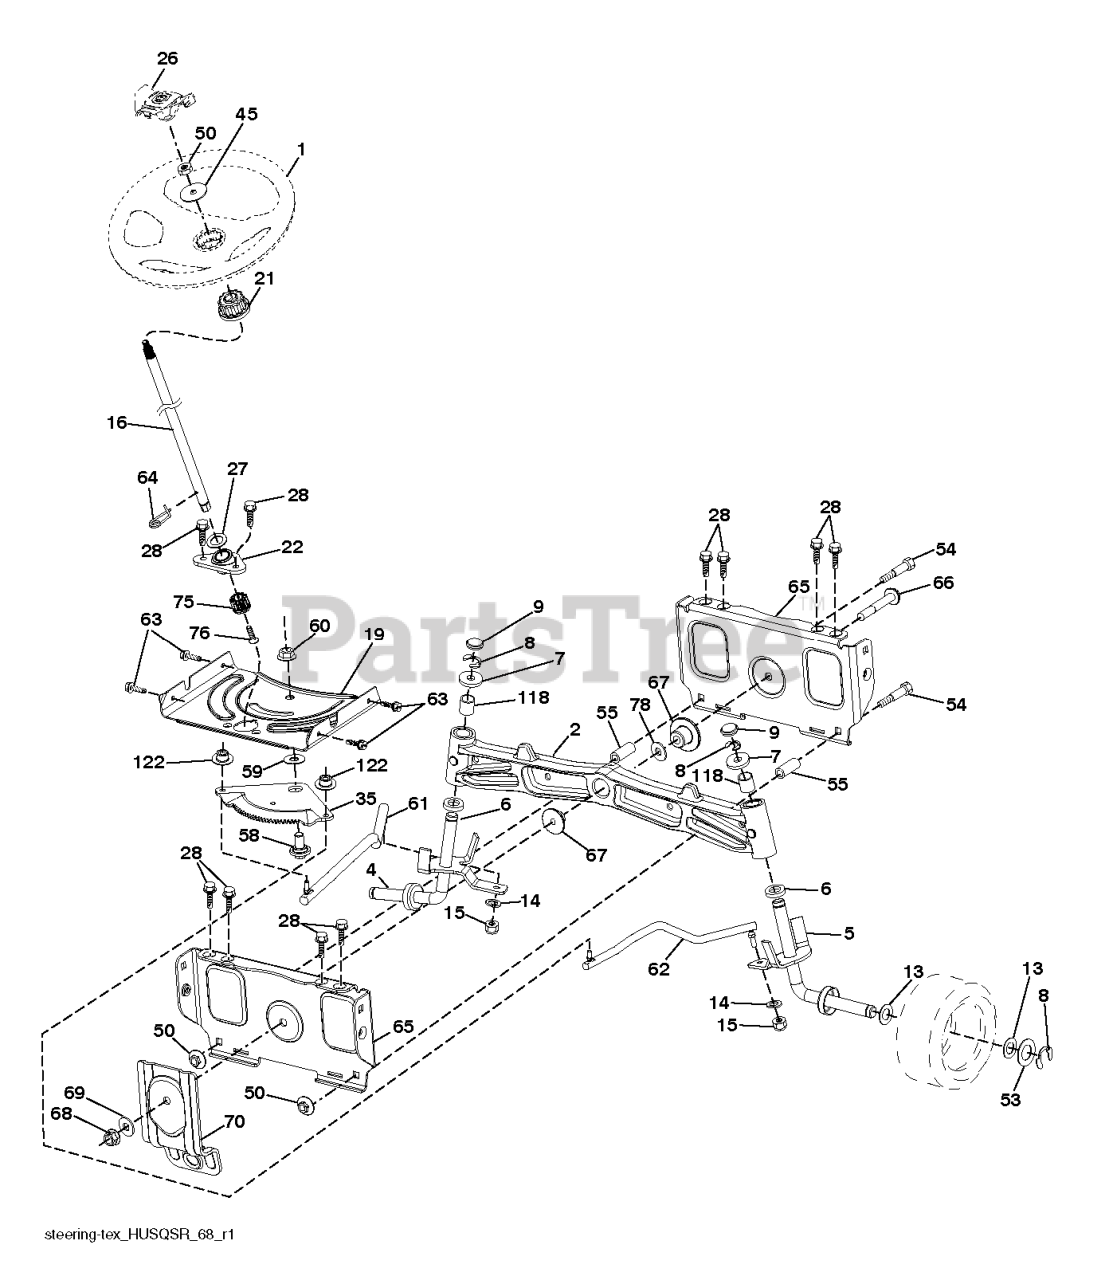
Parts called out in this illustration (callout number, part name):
1	WHEEL.STEER.HUSQ.SR.498.OVMLD
2	AXLE.SVC.ASM CAST IRON.TEX
4	SPINDLE.ASM.LH
5	SPINDLE.ASM.RH
6	THRUST WASHER
9	CAP.SPINDLE.BLACK
14	SLW 3/8 STD
15	NUT CROWNLOCK 3/8-24
16	SHAFT.STEER.2HIGH.SPLND.PLATED
19	PLATE.STEER.DDL.NLT/NG
21	ADAPTER.WHEEL.STEER.SPLND.ALUM
22	BEARING.SHAFT.STEER.LOWER.625
26	INSERT.CAP.WHL.STRG.HUSQ.PREM
28	SCREW, 3/8-16X3/4
35	GEAR.SECTOR.PLATE.DDL.
45	WASHER.3/8ID.2-3/8OD.12GA.PLTD
50	NUT LOCK FLG 3/8-16 UNC
53	WASHER.HARDENED
55	SPACER.BRACE.AXLE
58	BOLT.SHOULDER.SECTOR.P
59	WASHER.THURST.SECTOR.S
60	NUT FLANGE LOCK 5/8-11
61	LINK.ASM.DRAG.ADJUST.LH.PLATED
62	LINK.ASM.DRAG.ADJUST.RH.PLATED
63	SCREW
64	RETAINER.CLIP.SPRING.S
65	BRACE.AXLE.FRONT.NLT/N
66	BOLT HEX FGHD 7/16-14 X 3 SERR
67	BUSHING.PM.FRONT AXLE
68	NUT.LOCK.FLANGE.7/16
69	WASHER.1.5X.505X.118
70	BRACKET.FRT.DECK.SUSP.RR.MT431
75	PINION.ZINC PLATED
76	SCREW HEAD SOCKET LRVB
78	THRUST WASHER
118	BUSHING, AXLE CAST
122	CAP.GEAR.SECTOR.TEX
